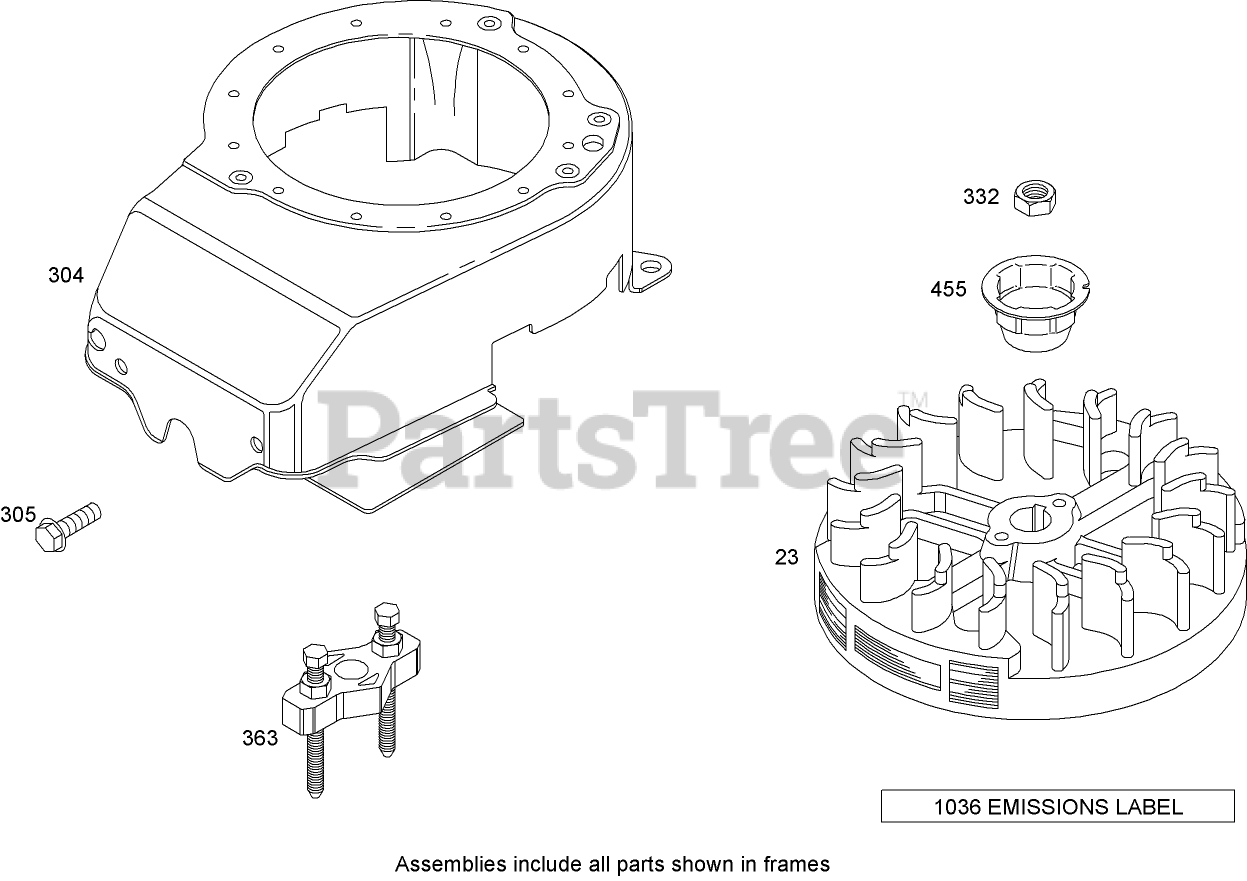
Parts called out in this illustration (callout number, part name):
23	Flywheel
304	Housing-Blower
305	Screw
332	Nut
363	Puller-Flywheel
455	Cup-Flywheel
1036	Loose Parts Package
